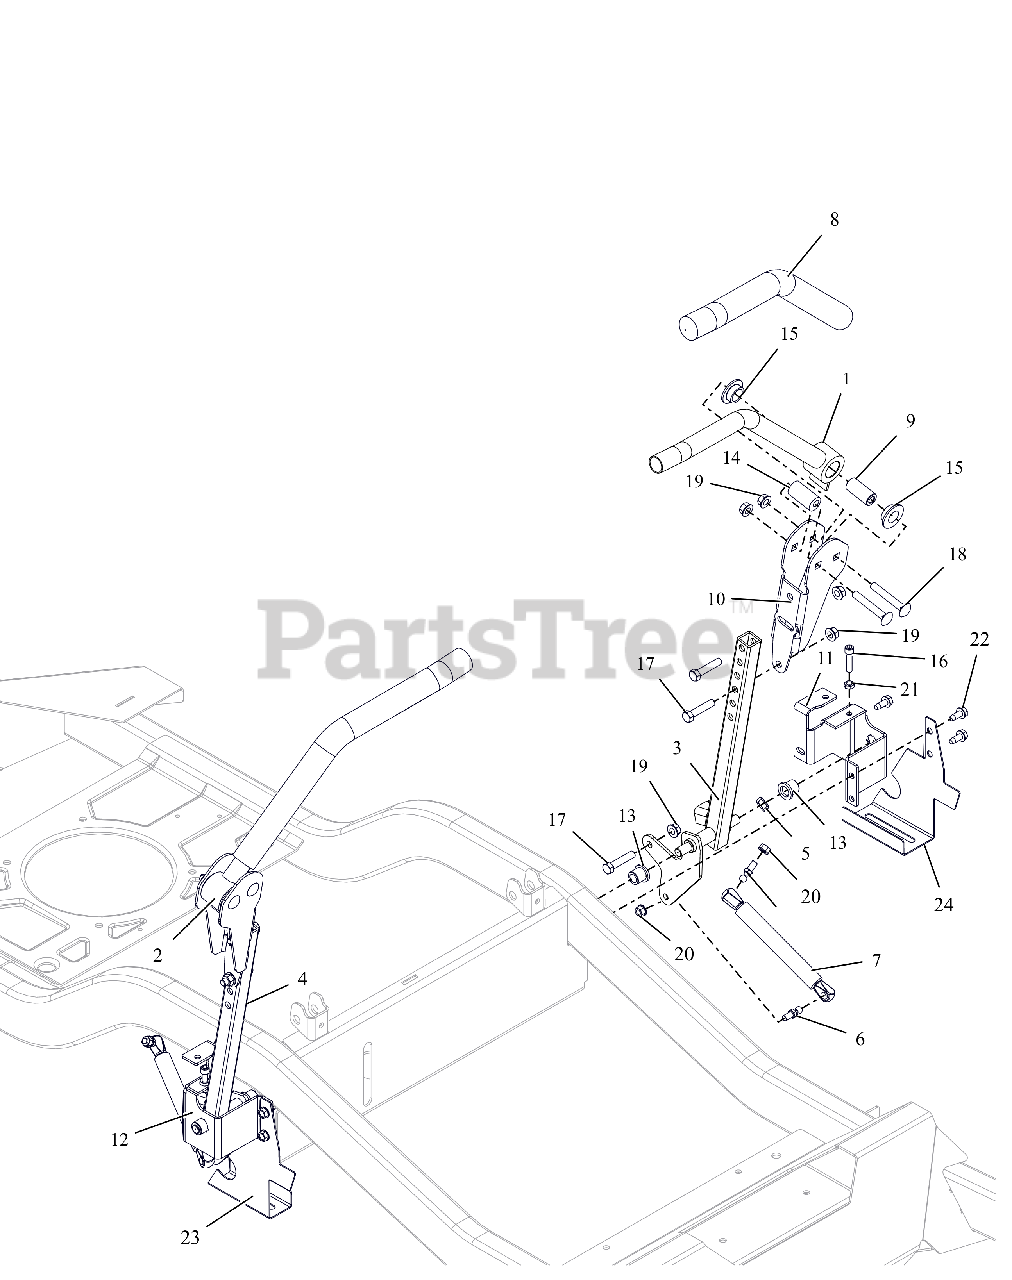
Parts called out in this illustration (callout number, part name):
1	WLDMT, CONTROL HANDLE- BLK
2	WLDMT, CONTROL HANDLE- BLK
3	WLDMT, STEERING LH
4	WLDMT, STEERING RH
5	WAVE WASHER .531X.781X.125FH
6	STUD- BALL
7	DAMPER
8	GRIP, HANDLEBAR
9	SPACER, STEERING ARM
10	ADJ UPPER CONTROL ARM BRKT-BLK
11	BRKT, STEERING ARM MOUNT -LH
12	BRKT, STEERING ARM MOUNT -RH
13	BHSG-FLG .500X.750X.750X.125
14	BSHG, ECCENTRIC.406X.875X1.625
15	BSHG-FLG .762X1.48X.44 NYL
16	SHCS .312-18 X 1.25 GR8 YWZC
17	BLT, HEX .38-16X1.75 G5 ZCC
18	BLT, RHSSN.38-16X2.50 G5 ZCC
19	NUT-LK-TOP-FLG .38-16 ZC120
20	NUT-LK-TOP-FLG .312-18 GF ZCC
21	NUT-JAM .312-18 G2 ZCC
22	SCR,TAP .312-18X.75 HWH TR ZCC
23	GUARD, FRAME RAIL BELT RH
24	GUARD, FRAME RAIL BELT LH
